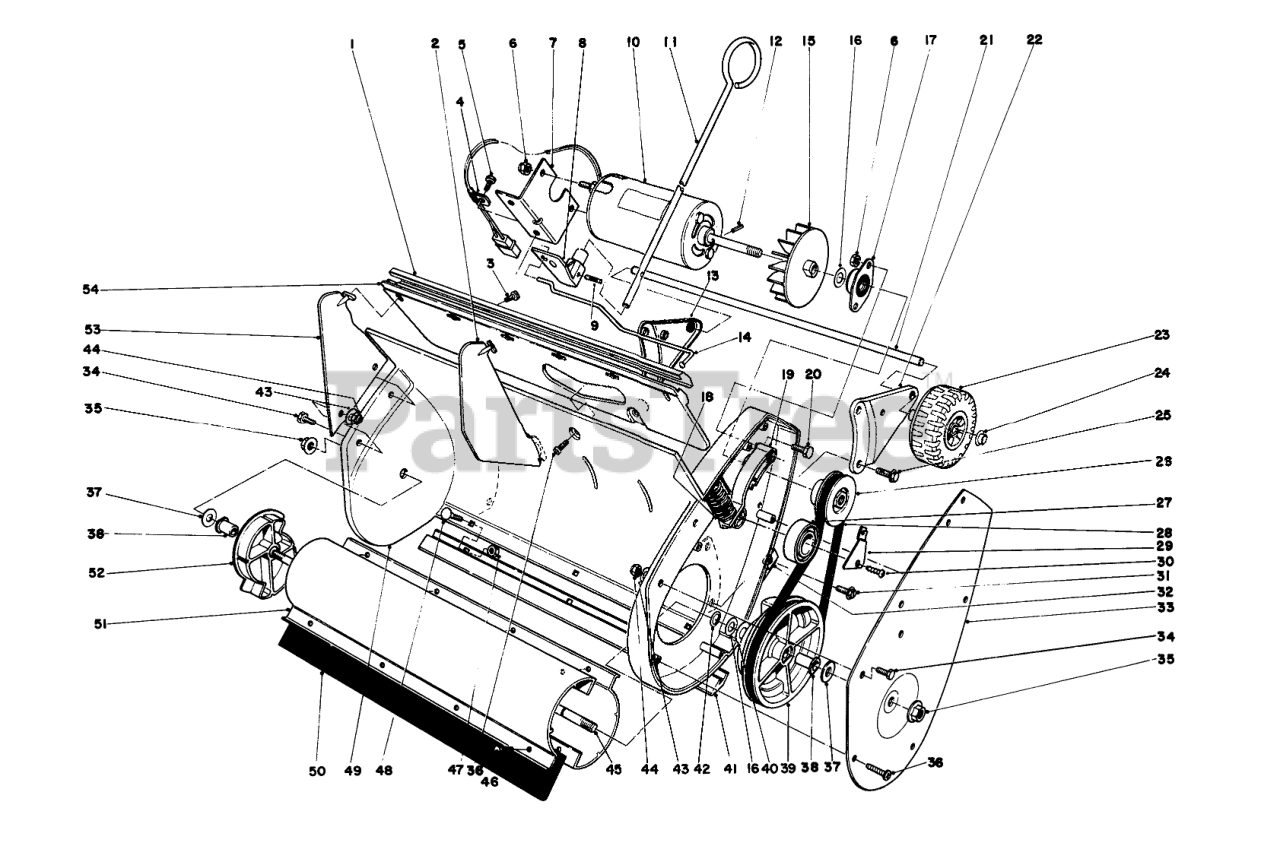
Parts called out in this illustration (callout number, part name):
1	MOULDING
2	VANE INNER
3	10-16 X 3/8 THDG SCREW
4	CLIP-CLOSED, INSULATED
6	NUT-LOCK, NI
7	MOUNTING BRKT B
8	VANE ADJ BRKT
9	GROOVE PIN
10	Motor
11	VANE ADJ ROD
12	SPRING PIN
13	Bracket R.H.
14	Linkage Vane Adjustment
16	WASHER-THRUST
17	SIDE FLANGE BRG
18	IDLER COMP. SPRING
19	IDLER ARM
20	SCREW-HH
21	AXLE SHAFT
22	Wheel Bracket L.H.
23	S-120 WHEEL
24	PUSHNUT-CAP, WASHER
25	Screw
26	DRIVE PULLEY
27	BEARING-BALL
29	IDLER PULLEY RETAINER
30	#8 X .625" PHILPS PAN H
31	SCREW-HWHTF
32	NUT-TYPE J
33	Cover-Belt Case
34	SCREW-HWH
35	NUT-HF
36	Screw
37	THRUST WASHER (THICK)
38	BUSHING ROTOR
39	Pulley-Driven
40	Washer
41	SCRAPER-SERVICE
42	RING-RETAINING
43	Washer
44	NUT-LOCK, NI
45	ROTOR SHAFT
46	Screw
47	NUT-KEPS
48	SCREW-CARR
49	HOUSING, S-120 HID
50	Blade-Rotor
51	ROTOR
52	END CAP ROTOR
53	VANE OUTSIDE
54	Vane Mount
